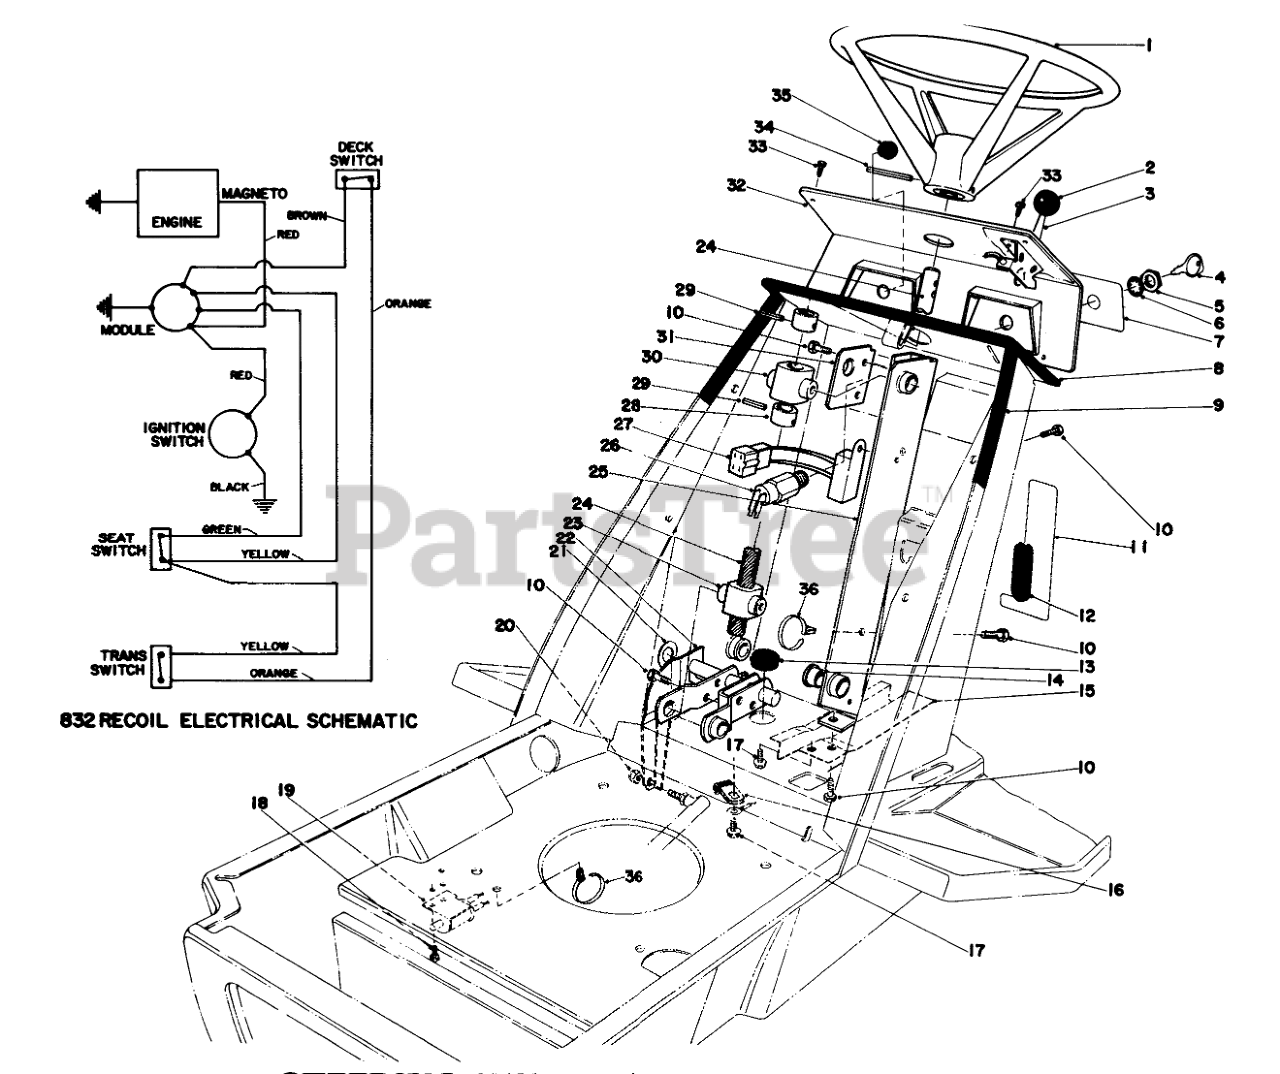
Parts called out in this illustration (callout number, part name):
1	Steering Wheel
2	KNOB-CONTROL
3	Throttle Control (Incl. Ref. #2)
4	Key
5	NUT-HH
6	WASHER-TOOTH, INTERNAL
7	DASH PANEL DECAL
8	Seal-Extrusion
9	Seal-Extrusion
10	SCREW-HWHTF
11	Decal-Deck
12	EDGE MOULDING
13	GROMMET
14	BEARING-FLANGE
15	WIRE HARNESS SHLD B
16	CLIP-FUEL LINE
17	SCREW-HWH
18	SCREW-TAPTITE
19	DECK INTERLOCK SWITCH
20	Nut
21	WASHER
22	STEERING LINK WA BO
23	FOLLOWER STEER SHAFT
24	Steering Shaft
25	STRG BRKT B
26	Ignition Switch (Incl. Ref. #5 & 6)
27	Module-Interlock
28	STRG SHAFT COLLAR
29	PIN-SPRING
30	BRG STEERING SHAFT
31	STRG BRG SUPPORT
32	DASH PANEL
33	SCREW-HWHTF
34	PIN-ROLL
35	Domed Plug
36	TIE-MOUNT, PUSH
